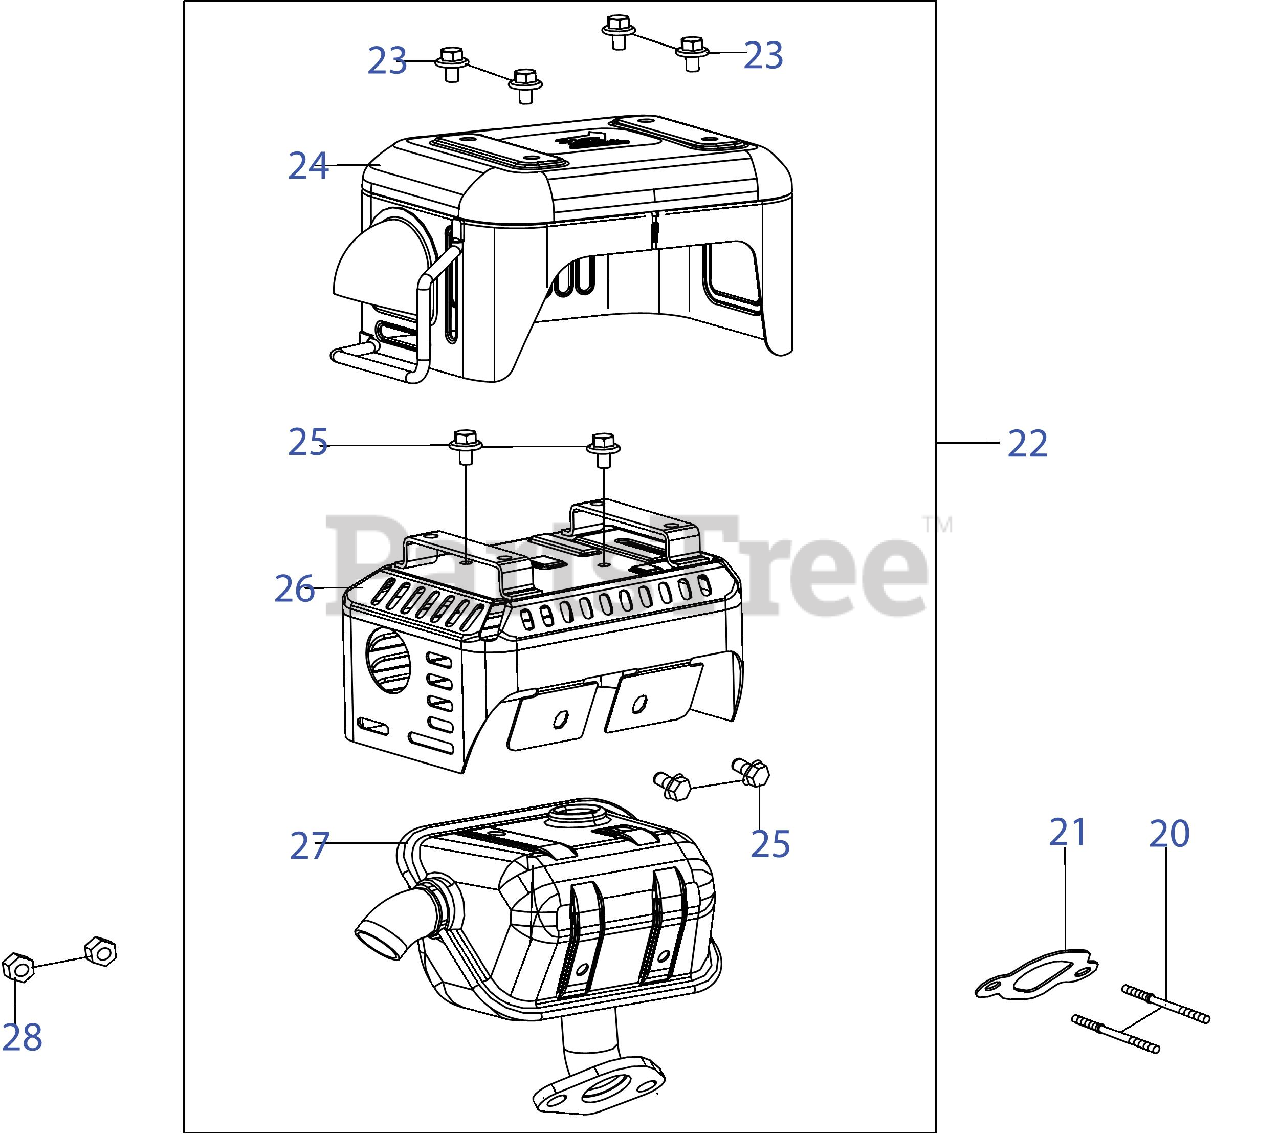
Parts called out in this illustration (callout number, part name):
20	Stud M8x34
21	Muffler Gasket
24	Muffler Guard
25	Bolt M5x12
26	Muffler Shield
27	Muffler Body
